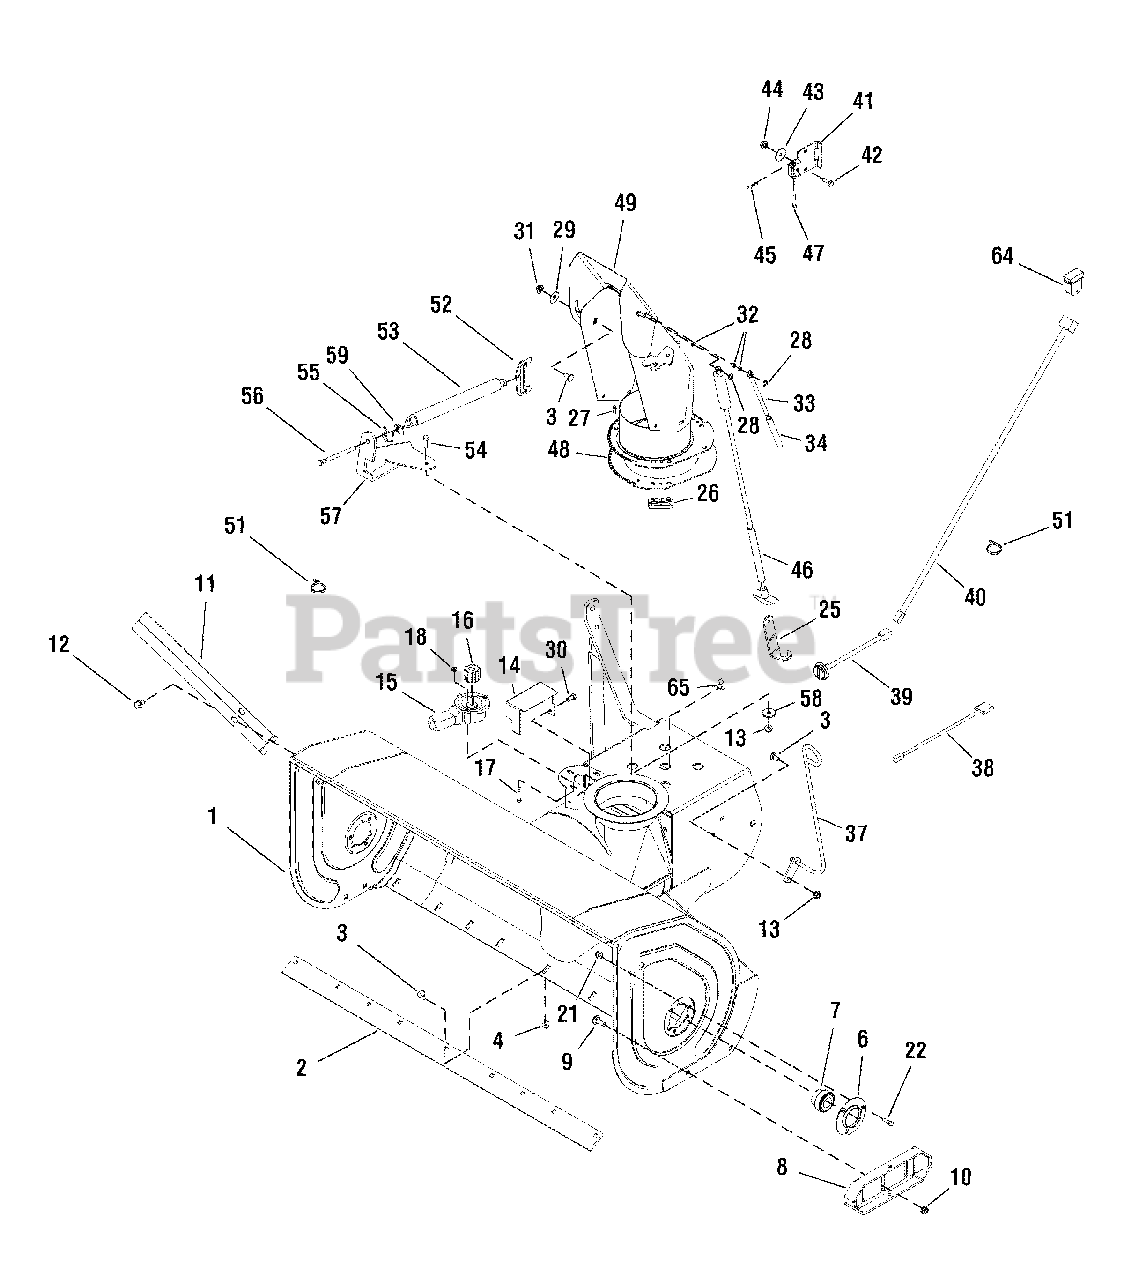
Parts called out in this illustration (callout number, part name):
1	AUGER HOUSING ASSEMBLY, 42"
2	SCRAPER BAR, 42"
3	BOLT, Carriage, 5/16 - 18 x 3/4
4	LOCKNUT, Flange, 5/16 - 18
6	BEARING, Flange
7	BEARING, Cartridge
8	SKID SHOE
9	BOLT, Carriage, 3/8 - 16 x 1
10	NUT, ESNA Flange, 3/8 - 16
11	DRIFT CUTTERS
12	SCREW, Hex Washer Head Taptite, 5/16 - 18 x 3/4
13	NUT, Keps Washer, 5/16 - 18
14	COVER, Gear
15	MOTOR, Electric
16	GEAR, Pinion
17	SCREW, Hex Washer, #10 - 24 x 1-1/4
18	NUT, Hex Keps, #10 - 24
21	NUT, Hex Flange Whizlock, 5/16 - 18
22	SCREW, Hex Head, 5/16 - 18 x .62
25	BRACKET, Cable
26	CHUTE RETAINERS
27	SCREW, Plastite
28	NUT, Push, 1/4
29	WASHER, Nylon
30	SCREW, Hex Washer Head Taptite, 1/4 - 20 x 3/8
31	NUT, Hex Flange ESNA, 5/16 - 18
33	ROD, Spring
34	SPRING, Compression
37	GUIDE ASSEMBLY, Cable
38	HARNESS, Spout Rotator
39	HARNESS, Power Outlet
40	HARNESS ASSEMBLY, Chute
41	BRACKET, Cable Mount
42	CAPSCREW, 1/4 - 20 x 7/8
43	WASHER, Special
44	NUT, Hex Keps, 1/4 - 20
45	HAIRPIN, 1/16
46	CABLE ASSEMBLY
47	PIN, Flat Head
48	GEAR, Chute
49	CHUTE ASSEMBLY
51	CABLE TIE
52	SPRING ANCHOR
54	CAPSCREW, 5/16 - 18 x 1
55	RETAINER, Spring
56	CAPSCREW, 5/16 - 18 x 4-1/2
57	SPRING ANCHOR ASSEMBLY
59	NUT, Pushpal, 5/16 - 18
64	SWITCH, Chute Control
